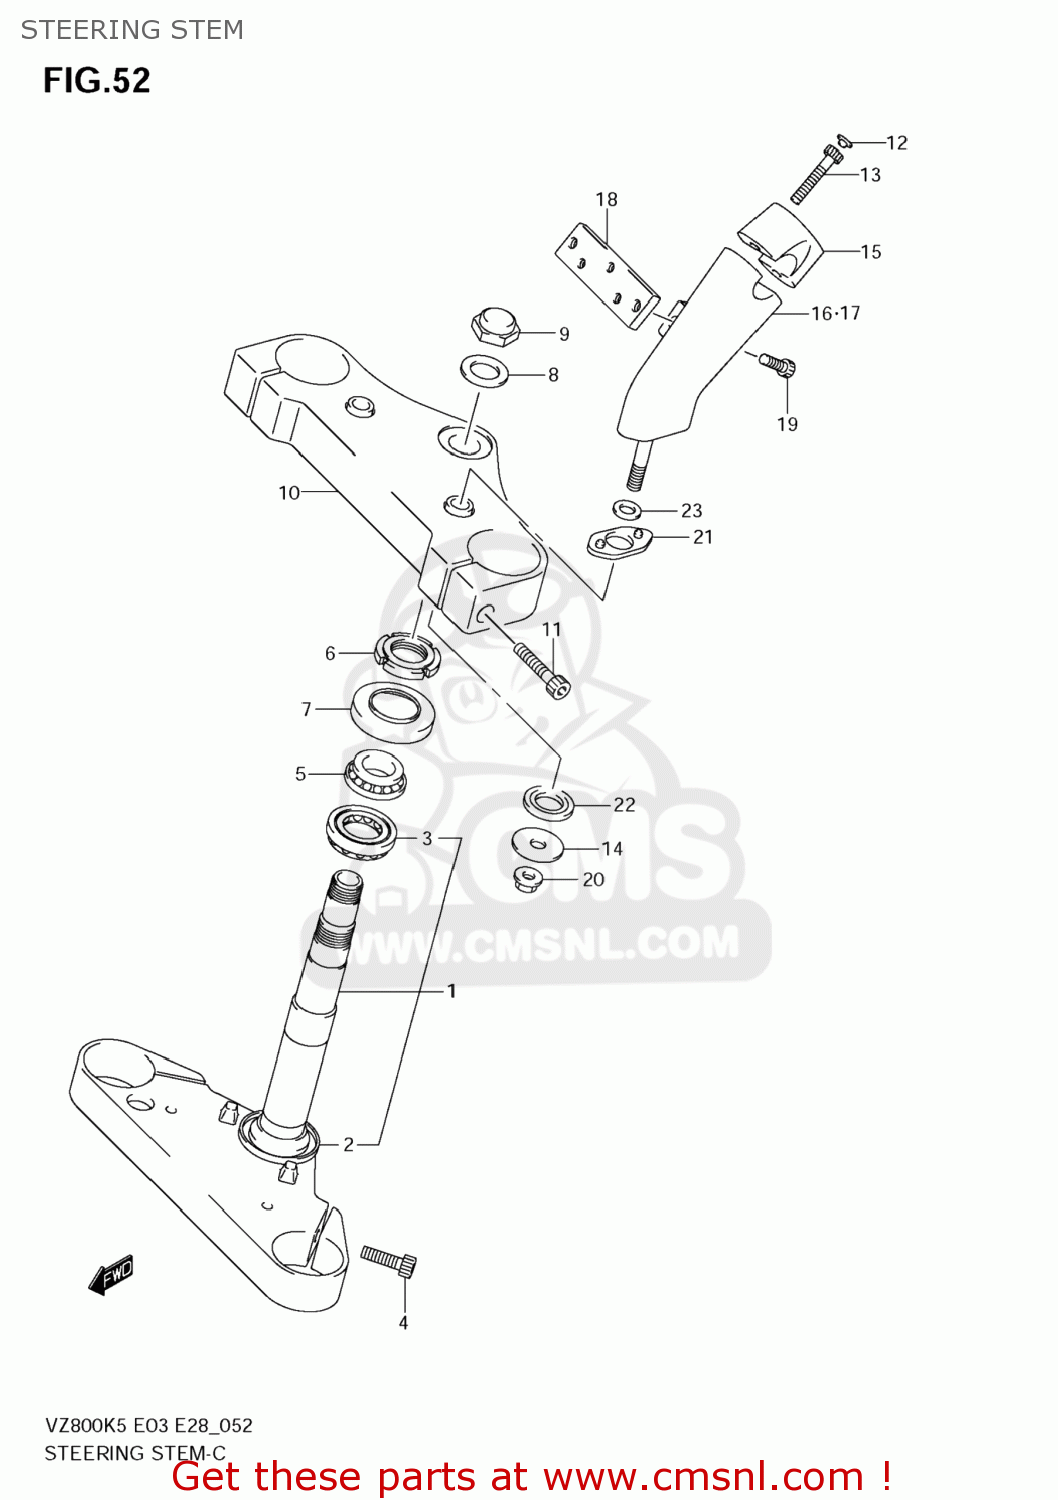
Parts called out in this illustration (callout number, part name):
1	BRACKET,UNDER
2	SEAL,STEERING LWR
3	BEARING(30X55X17)
4	BOLT
5	BEARING(25X47X15)
6	NUT,STEERING STEM(25X44X10)
7	DUST SEAL,STEERING UPR
8	WASHER(22.5X35.9X1.6)
9	NUT,CAP
10	BRACKET,UPR
11	BOLT,LWR
12	CAP(OD:11)
13	BOLT,BRACKET LOW
14	WASHER
15	HOLDER,HANDLE
16	HOLDER,HANDLE,R
17	HOLDER,HANDLE,L
18	BRIDGE
19	BOLT
20	NUT
21	RUBBER,HANDLE HOLDER
22	RUBBER,HANDLE HOLDER
23	WASHER
